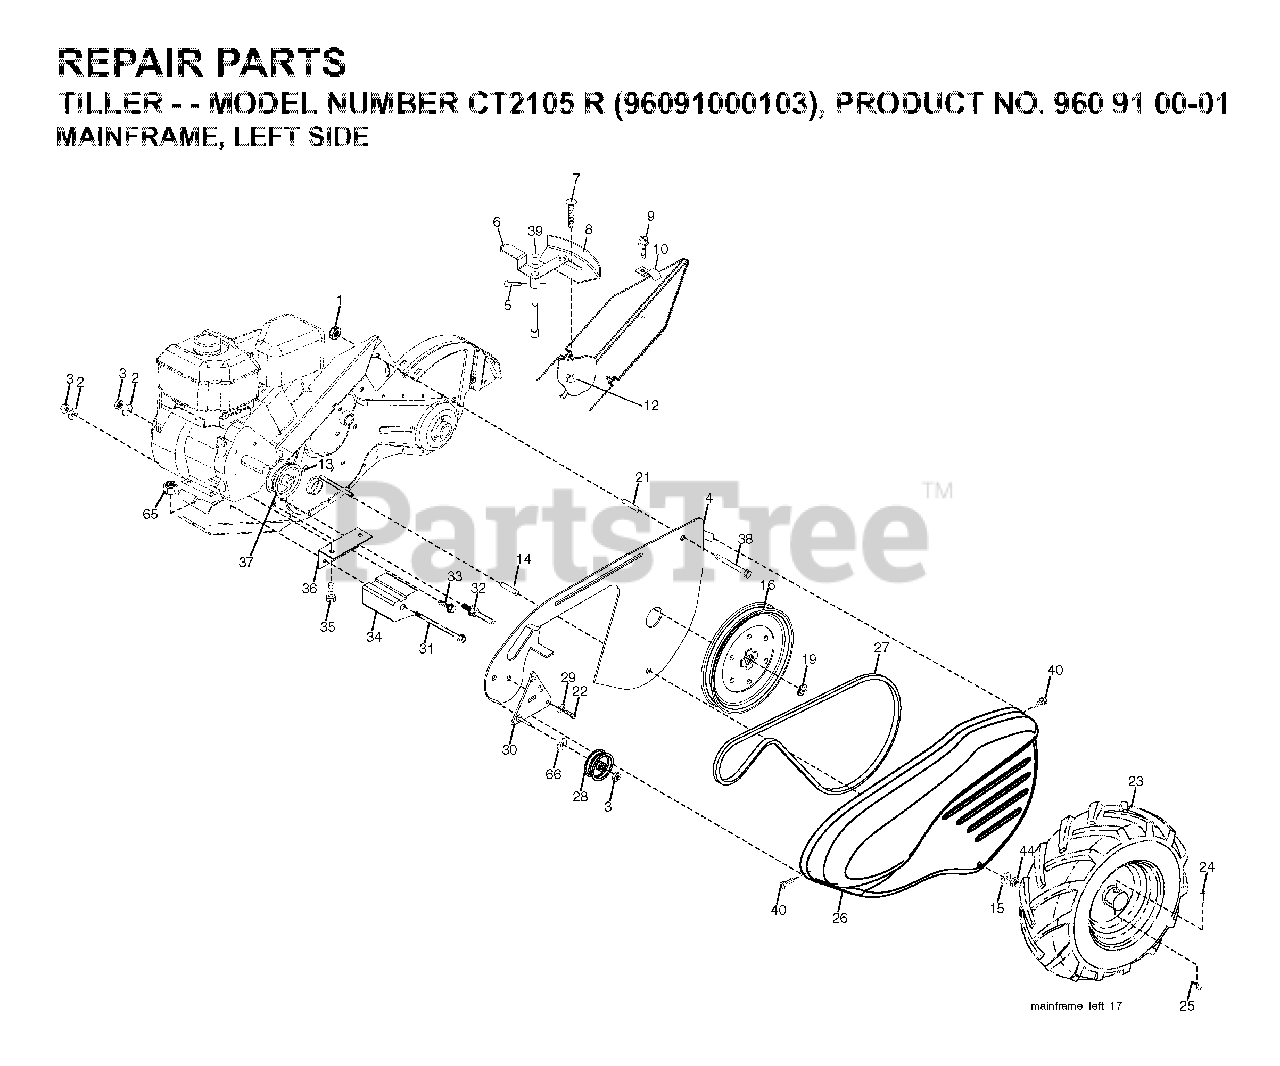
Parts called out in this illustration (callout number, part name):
1	LOCKNUT-FLANGE 5/16-18
2	WASHER, LOCK 3/8
3	NUT.HEX.3/8-16UNC
5	PIN.SPIROL.FLARED
6	LEVER ASM CRT
9	TAPPING SCREW
10	CONDUIT CLIP T
12	NUT
13	SET SCREW **
14	SPACER-SPLIT.327 X .42
15	WASHER
16	SHEAVE, TRANSMISSION
19	RETAINING RING LT
21	SPACER CRT
24	RIVET,DRILLED
25	RETAINER M
27	V-BELT
28	PULLEY-IDLER TI
29	KLIP RING
30	BRACKET.ASM.IDLER
31	BOLT.FIN.HEX.3/8-16UNC
32	SHIFT ARM CRT
33	BOLT
34	COUNTERWEIGHT.LH.CRT
35	BOLT, HEX 5/16-18X1-3/4
36	BRACKET LH CRT
37	ENGINE PULLEY
38	BOLT
39	CAP.PLUNGER.BLACK
40	SCREW.HEX.WSH.SLT.#10-24X.50
44	NUT.71038.31-18.HEX.NYLOCK
65	LOCKNUT-FLANGE 5/16-18
66	WASHER
5321243-66	RIM
5321247-18	VALVE STEM LT
